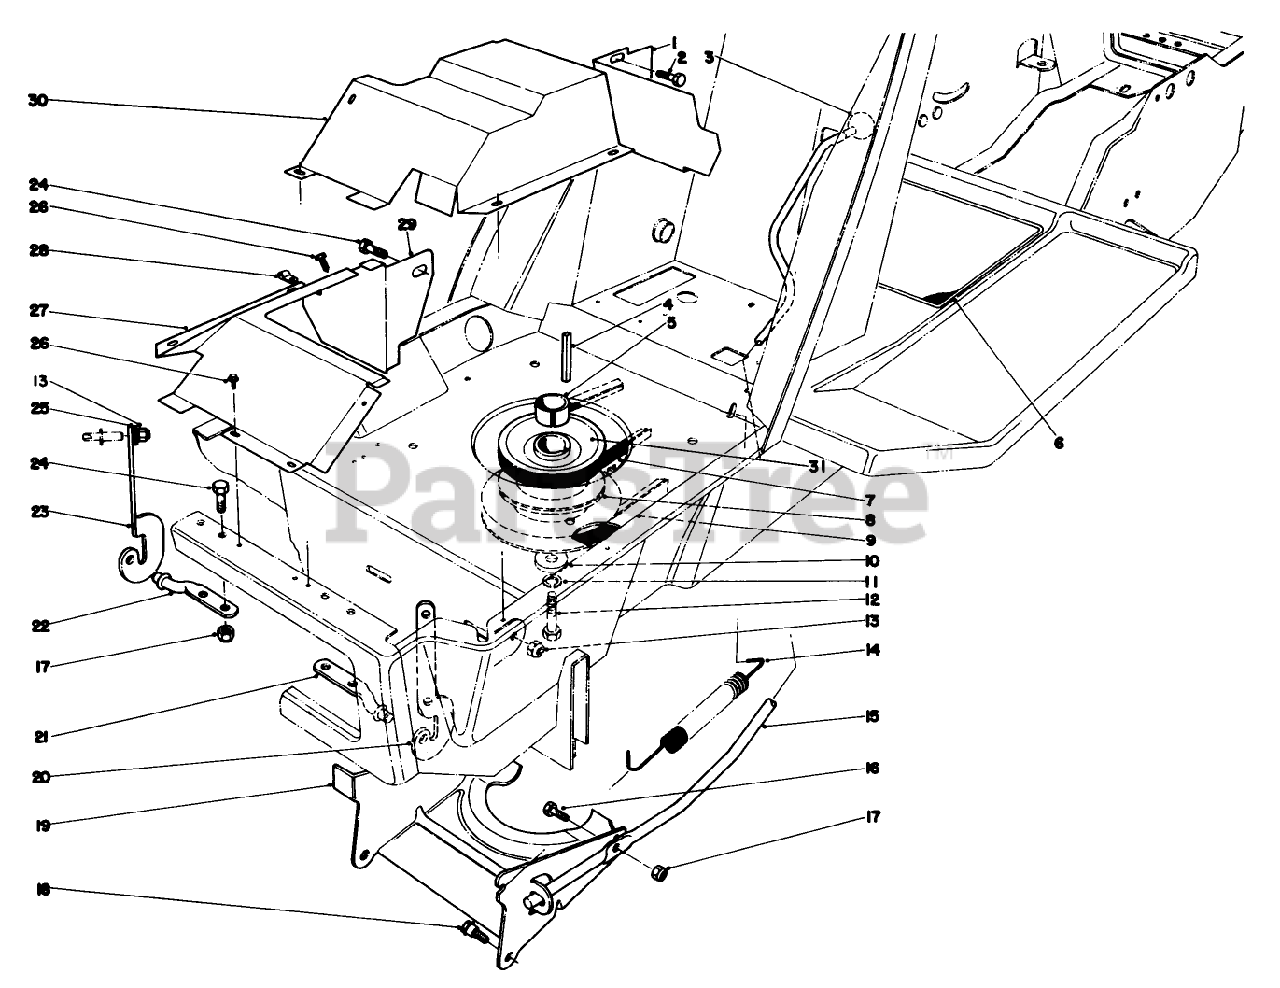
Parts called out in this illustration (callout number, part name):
1	EXH SHIELD SUPT B
2	SCREW-HH
4	KEY-SQUARE
5	PULLEY SPACER
6	OPERATION DECAL
7	V BELT
8	Clutch & Brake Deck
9	V-BELT, ENG/DECK
10	WASHER
11	WASHER-LOCK
12	SCREW-HH
13	NUT-LOCK, CONE
14	TRACTION SPRING
15	Engagement Lever
16	SCREW-HH
17	NUT-LOCK, CONE
18	SCREW-SHOULDER
19	Actuator Clutch
20	L.H. HINGE BRACKET
21	LH HOOD HINGE PIN
22	Hinge Pin Hood R.H.
23	RH HINGE BRKT
24	SCREW-HH
25	SCREEN SUPT BRKT
26	SCREW-HWHTF
27	Heat Shield
28	CABLE CLAMP
29	Support Heat Shield
30	HEAT SHIELD WA B
31	TOP SHEAVE
